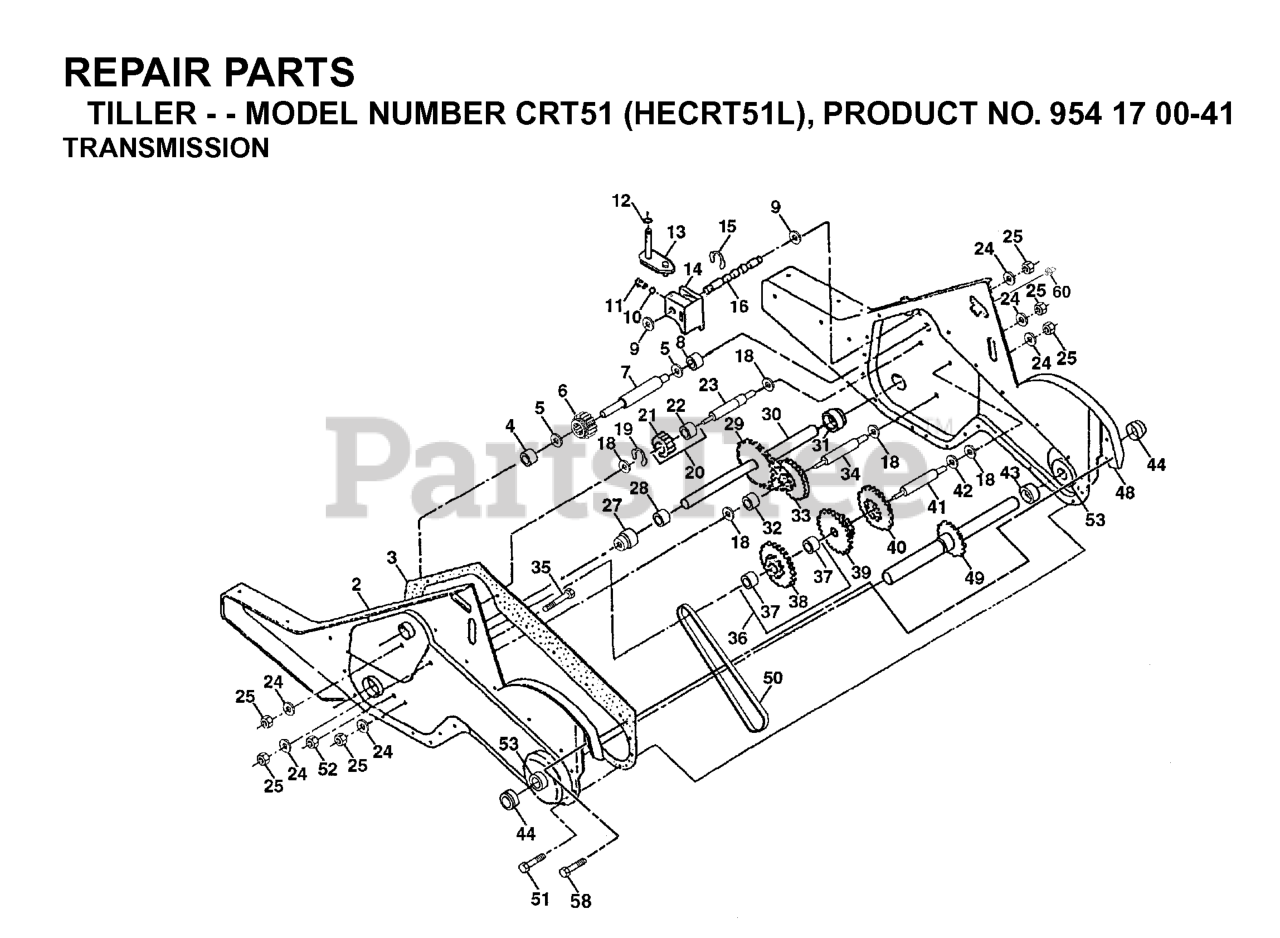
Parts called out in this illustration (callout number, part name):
1	TRANS SERV
2	GEAR CASE
3	GASKET
4	NEEDLE BRNG LT
5	THRUST WASHER
6	GEAR.PINION.INPUT
7	SHAFT.INPUT."D".TILLER
8	BEARING TI
9	WASHER, SEAL (2 2)
10	STEEL BALL KIT
11	SPRING-SHIFT CRT
13	BRACKET ASM.SHIFT.CRT
14	SHIFT FORK TI
16	SHAFT.SHIFTER.TILLER
20	GEAR ASSY CRT
21	GEAR-REV IDLR CRT
22	NEEDLE BEARING TI
24	LOCKWASHER
25	NUT.ASF.HEX.7/16
27	BEARING, SHAFT LH CRT
30	GROUND SHAFT ASS'Y
31	BEARING, SHAFT RH CRT
33	SPRCKT 8 GEAR CRT
34	SHAFT.SECONDARY.REDUCTION.CRT
35	SCRW WHIZ LOK CRT
36	SPROCKET.ASM.W/BEARING.TILLER
37	BEARING
38	SPROCKET, TINE
41	SHAFT.REDUCTION.TILLER
42	BRNG RACE T
44	SEAL ASM, OIL
48	GEARCASE, R.H. W/BEARING
49	TINE SHAFT
50	CHAIN.TILLER
51	SCREW
53	KIT.BEARING.TILLER.
58	BOLT SHOULDER 1/4-20 UNC X.875
60	ZERK M
